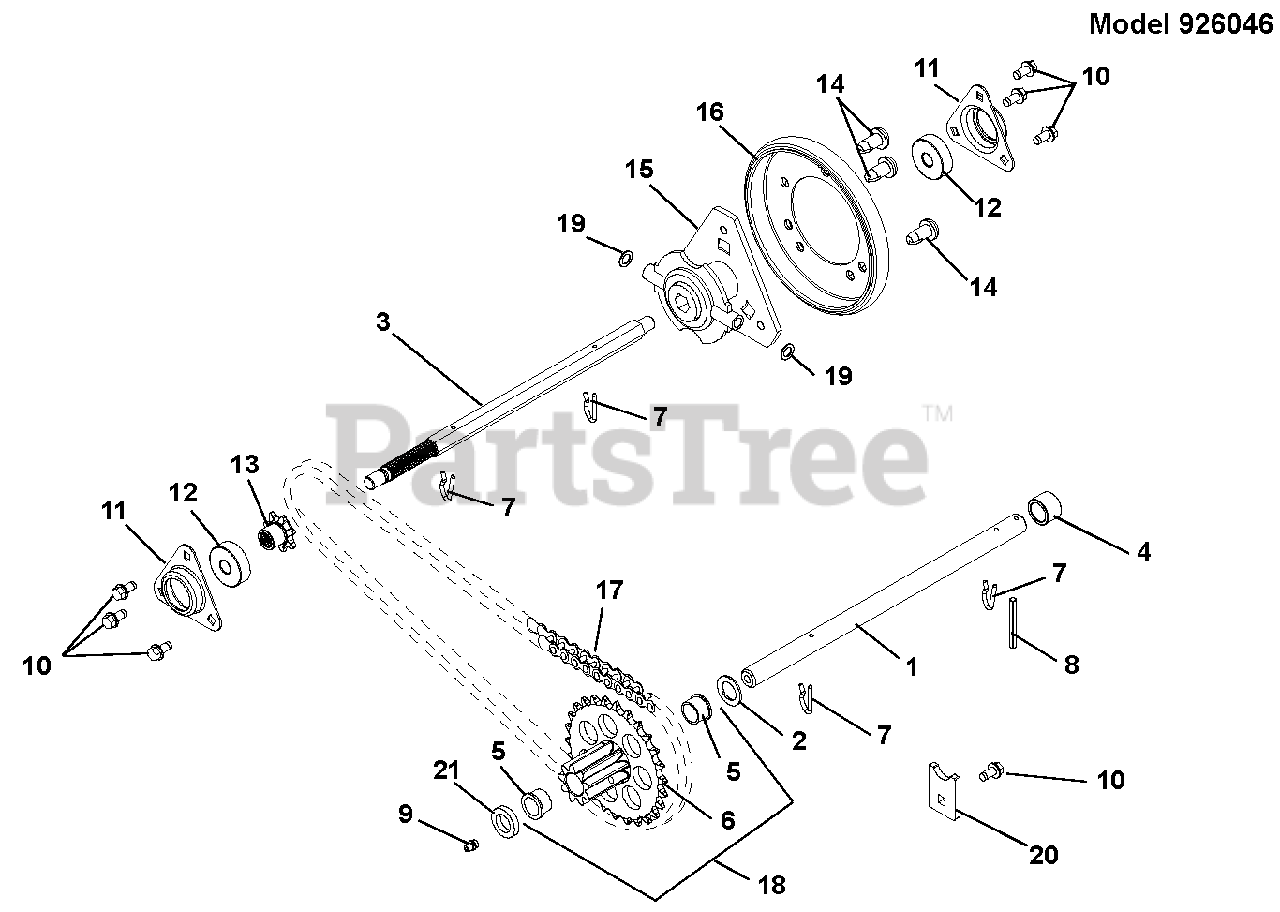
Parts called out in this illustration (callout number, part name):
1	Shaft, Pinion
2	Washer, Flat Steel .630 x 1.005 x .062
3	Shaft, Hex
5	Bushing, Flange (Included in Item 18)
6	Sprocket/Gear (Included in Item 18)
7	Pin, Spring Clip
8	Pin, Groove Type E .125 x 1.00
9	Zerk, Fitting .25 x .125 Drive-In
10	Screw, Tapping Hex Washer Head Thread Rolling .25-20 x .50
11	Flange, Bearing
13	Sprocket, Pinion
14	Screw, Tapping Serrated Round Head Torx .31-18 x .50
15	Carrier, Friction Disc
16	Friction Disc
17	Chain, Roller
18	Sprocket/Gear with Bushings (Includes Items 5 and 6)
19	Washer, Flat Steel .505 x 1.00 x .062
20	Tab, Anti-Rotation
21	Bushing, Sleeve
